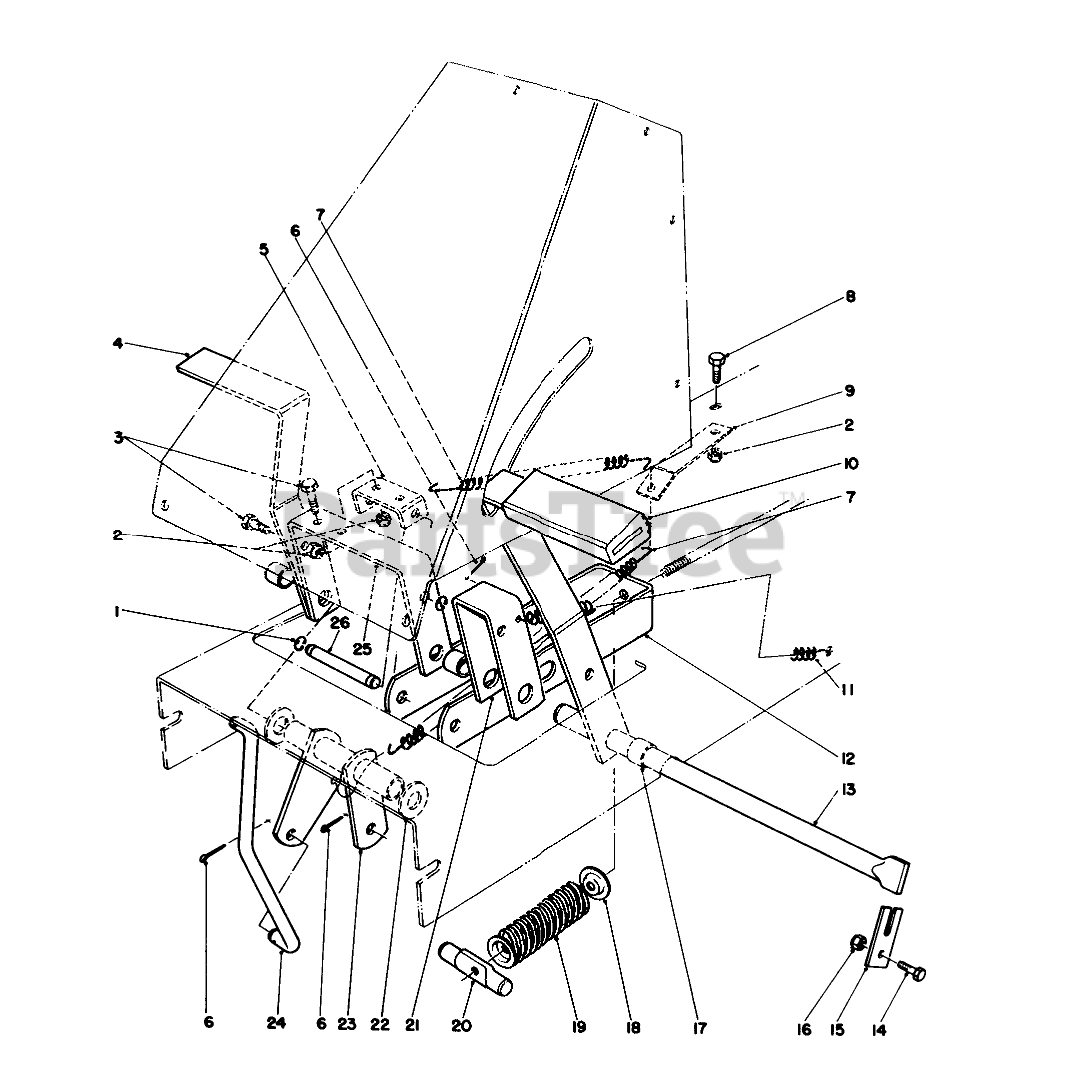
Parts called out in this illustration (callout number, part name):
1	E-RING
2	NUT-LOCK, NI
3	SCREW-HH
4	Pedal
5	Bracket-Brake
6	PIN-COTTER
7	TRACTION SPRING
8	SCREW-HH
9	Bracket-Spring Retaining
10	Pad-Foot Pedal
11	SPRING-EXTENSION
12	Bracket-Engagement
13	SHAFT-PEDAL PIVOT
14	SCREW-HH
15	RETAINER-SHAFT
16	NUT-LOCK, CONE
17	SPACER-PEDAL
18	RETAINER-SPR. TOP
19	SPRING-COMPRESSION
20	SHAFT-DECK ADJ.
21	Bracket-Clutch Pedal
22	WASHER-FLAT
23	Tube-Pivot
24	Arm-Engagement
25	Bracket-Brake Pedal
26	Pin-Clevis
